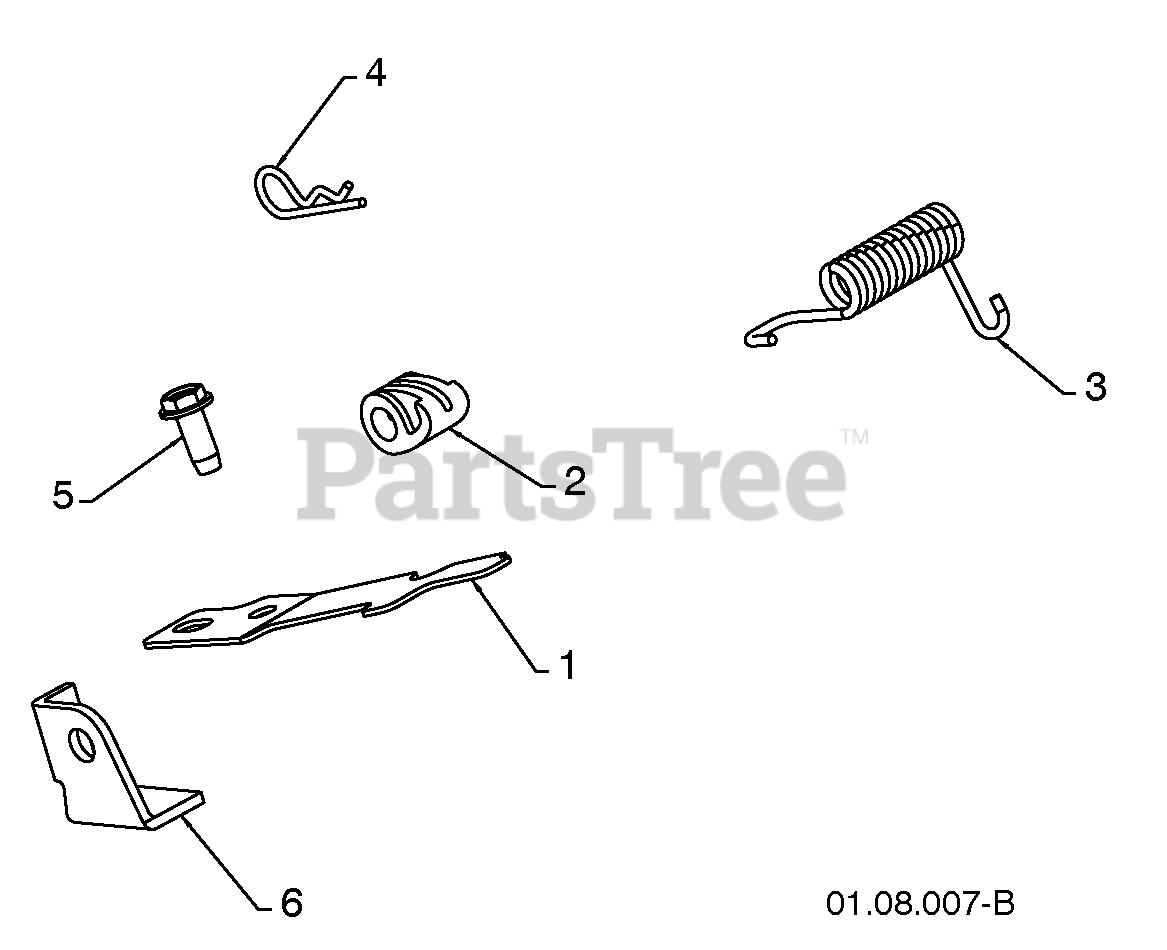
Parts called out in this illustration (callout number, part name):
1	INTERLOCK SPRING
2	INTERLOCK CAM
3	TORSION SPRING
4	RETAINER
5	SCREW 1/4-20 X .625
6	INTERLOCK STOP
